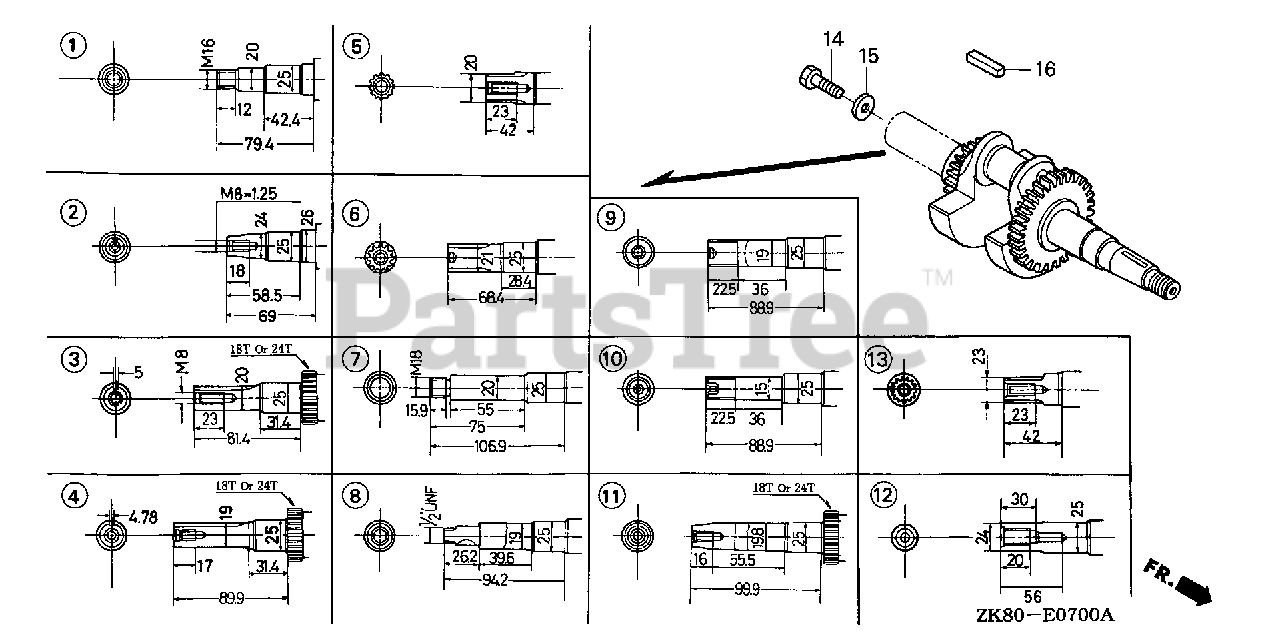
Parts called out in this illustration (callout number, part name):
3	CRANKSHAFT (24T)
3	CRANKSHAFT
16	KEY (5X5X33) (YELLOW)
